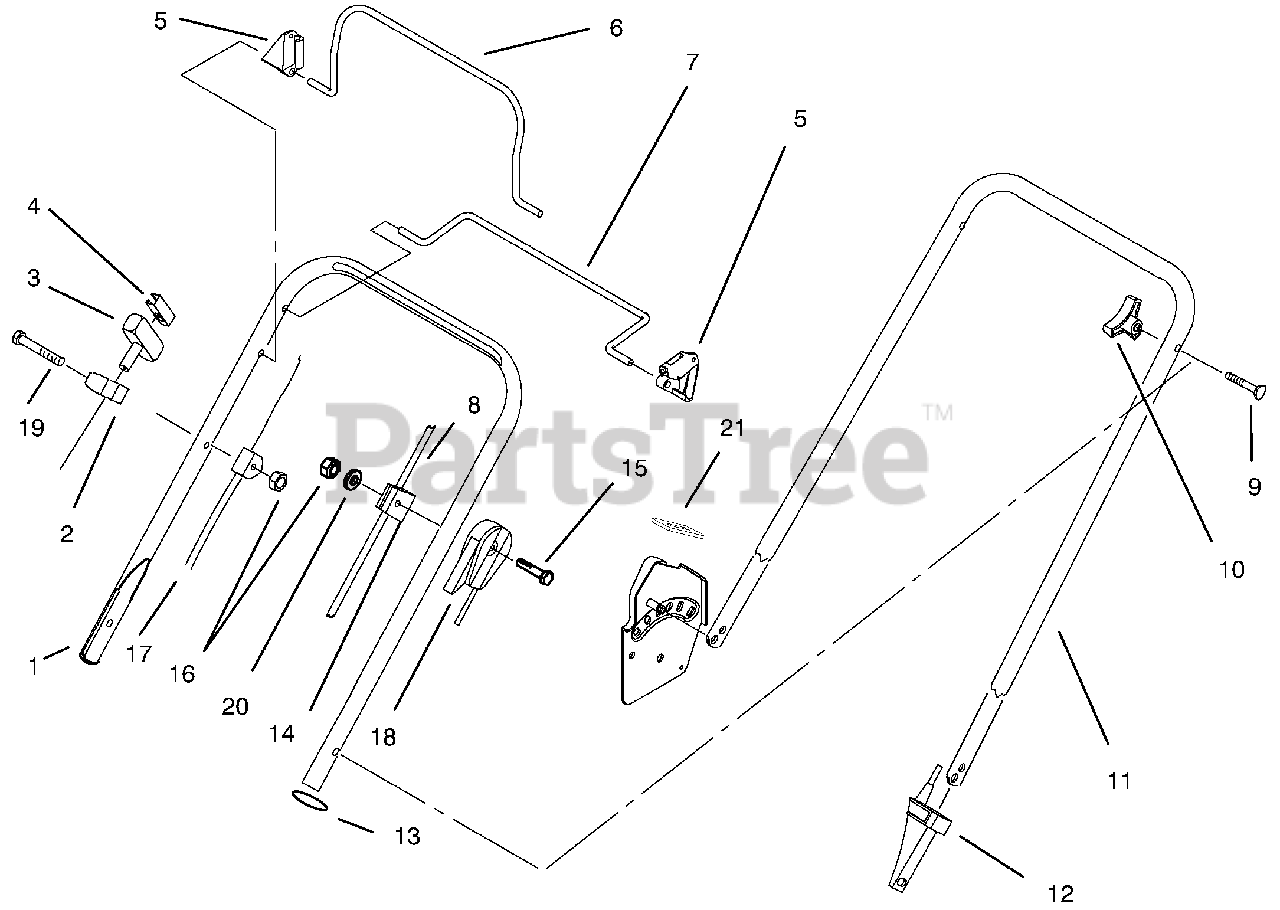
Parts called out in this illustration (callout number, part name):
1	Handle-Upper
2	Guide-Rope
3	Handle-Starter
4	Clip-Rope Insert
5	Stop-Pivot
6	Bail-Brake
7	Bail-Control (Model No. 10301 Only)
8	Cable-Traction
9	Screw-Handle
10	Knob-Handle
11	Handle-Lower
12	Anchor-Cable (Lower)(Model No. 10301 Only)
13	Tie Strap
14	Anchor-Cable (Upper)(Model No. 10301 Only)
15	Screw (Model No. 10201 Only)
17	Cable-Brake
18	Cable-Throttle
20	Washer (Model No. 10201 Only)
21	Guard-Handle (Qt'y 2 Model No. 10201 Only)
